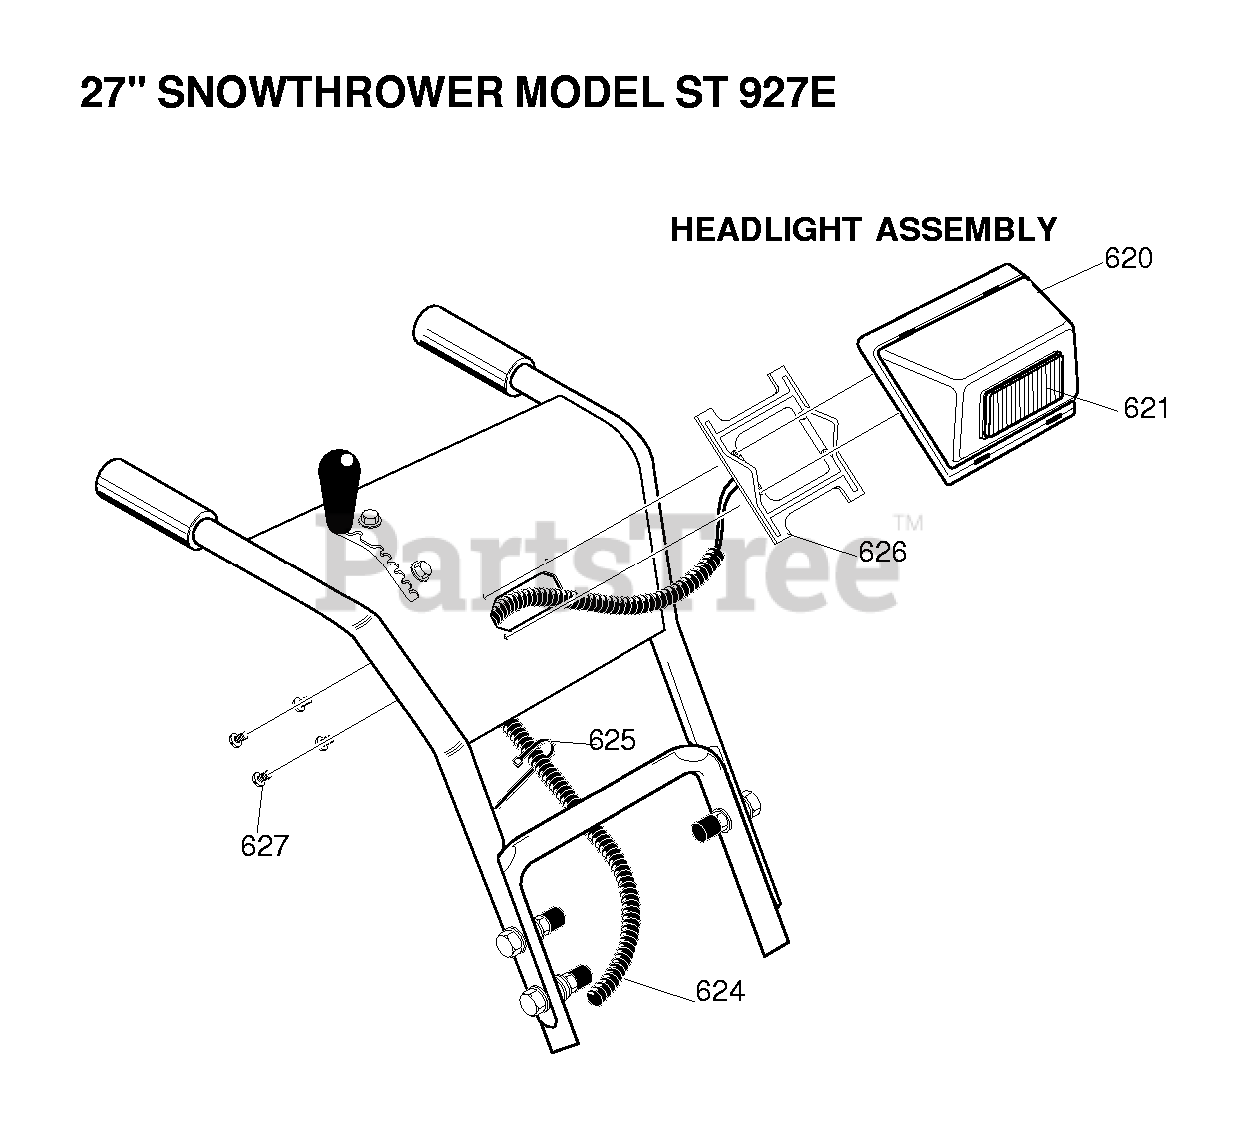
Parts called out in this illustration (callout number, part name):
620	HOUSING, LIGHT B/S
621	HEADLIGHT ASSY
624	ASSY, HEADLIGHT WIRE HARNESS
625	TIE,CABLE BLACK NYLON
626	BRACKET, LIGHT PANEL
627	SCREW, #8 X .75 PANTAPPLAST
